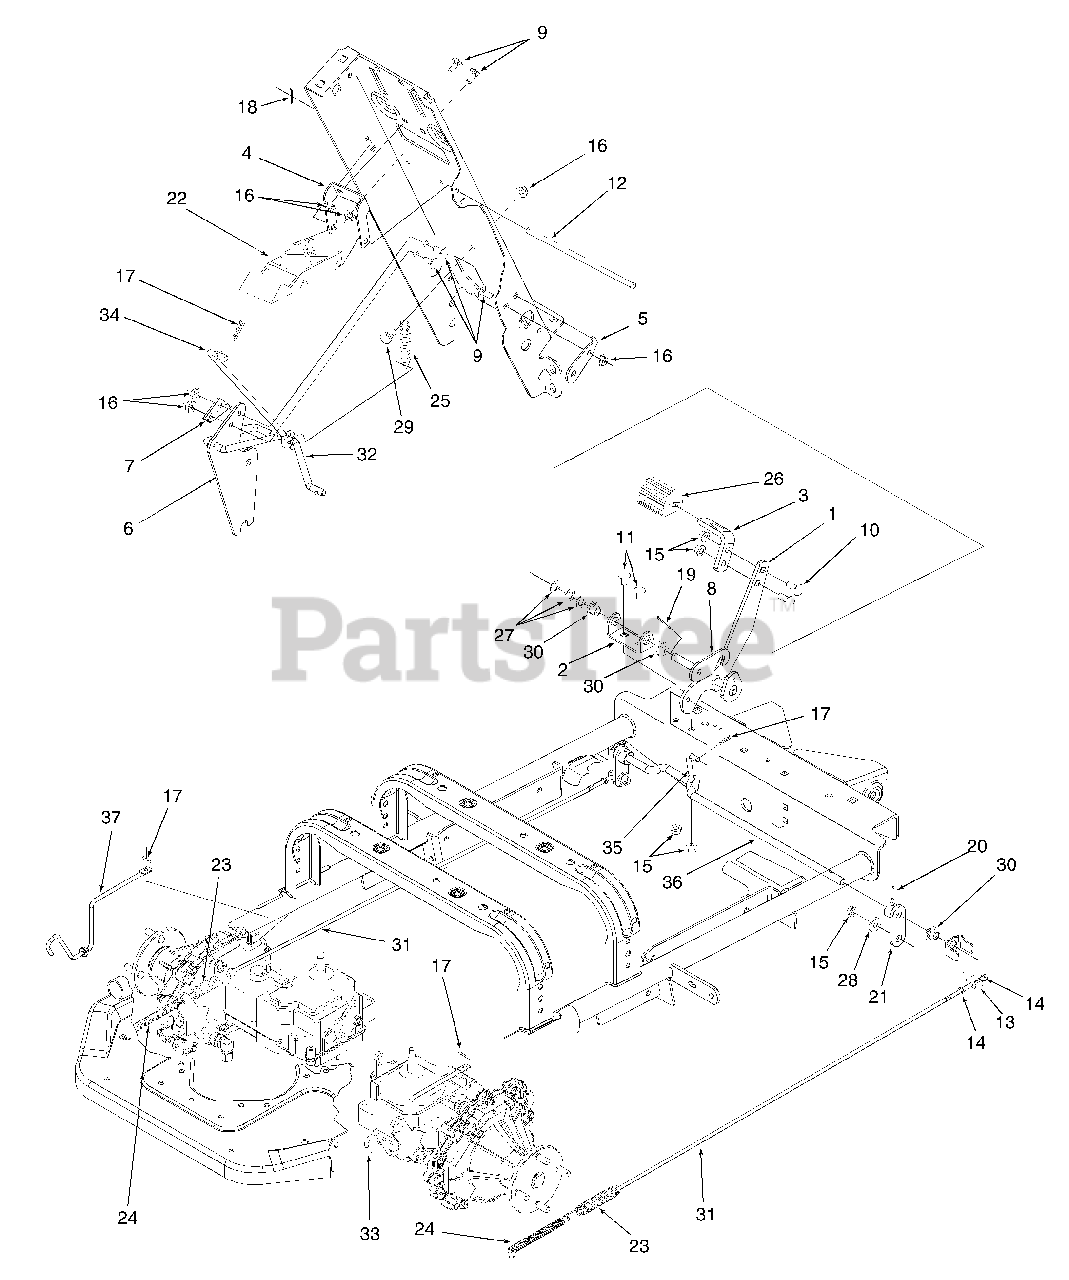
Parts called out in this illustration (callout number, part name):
10	Bolt, Carriage, 3/8-16 x 1.0 GR5
11	Bolt, Carriage, 3/8-16 x .75 GR5
12	Pin, Clevis, 1/4 x 6.65
14	Nut, Hex Jam, 1/4-28
15	Nut, Hex Flange Lock, 3/8-16
16	Nut, Hex Flange Lock, 1/4-20
17	Pin, Internal Cotter
18	Pin, Cotter, 1/16 x .75
19	Pin, Cotter, 3/32 x 1.25
20	Pin, Spiral, 3/16 x 1.5
22	Lever, Park Brake Engagement
23	Spring, Extension, .75 O.D. x 5.0
24	Spring, Extension
25	Spring, Extension, .5 O.D. x 2.25
26	Foot Pad, Brake
27	Washer, Flat, .536 x .930 x .05
28	Washer, Flat, .385 x 1.0 x .135
29	Bolt, Shoulder, .340 x .285:1/4-20
30	Bearing, Hex Flange, .506 I.D.
32	Rod, Park Brake Retaining
33	Rod, Hydro Pump Release RH
34	Rod, Park Brake
35	Rod, Park Brake Support
36	Rod, Brake Connecting
37	Rod, Hydro Pump Release LH
